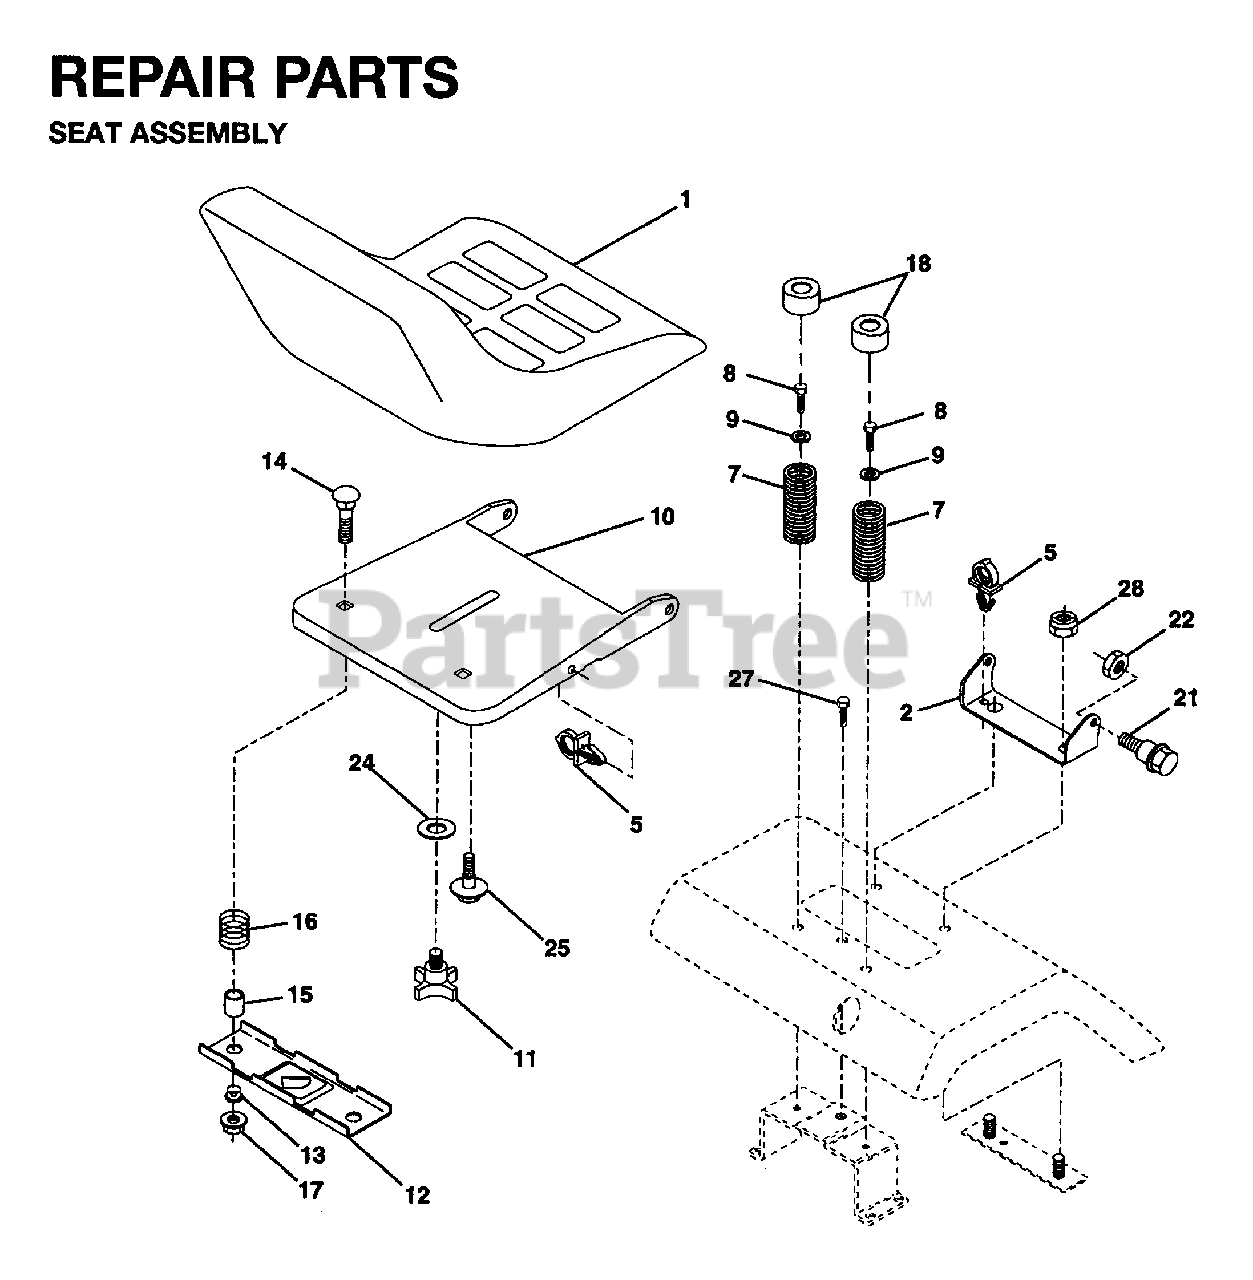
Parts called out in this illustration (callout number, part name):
1	SEAT
2	SEAT PIVOT BRKT
5	PUSH CLIP
7	SPRING COMPRESSION
9	WASHER
10	SEAT PAN
11	KNOB 1/2" YT
12	BRKT SWITCH
14	BOLT CARRIAGE 1/4-20X1 3/8
15	SPACER SPLIT
16	SPRING COMPRESSED
17	NUT.CROWNLOCK.1/4
18	CAP SPRING
22	LOCKNUT
25	BOLT,SHOULD
28	LOCKNUT
